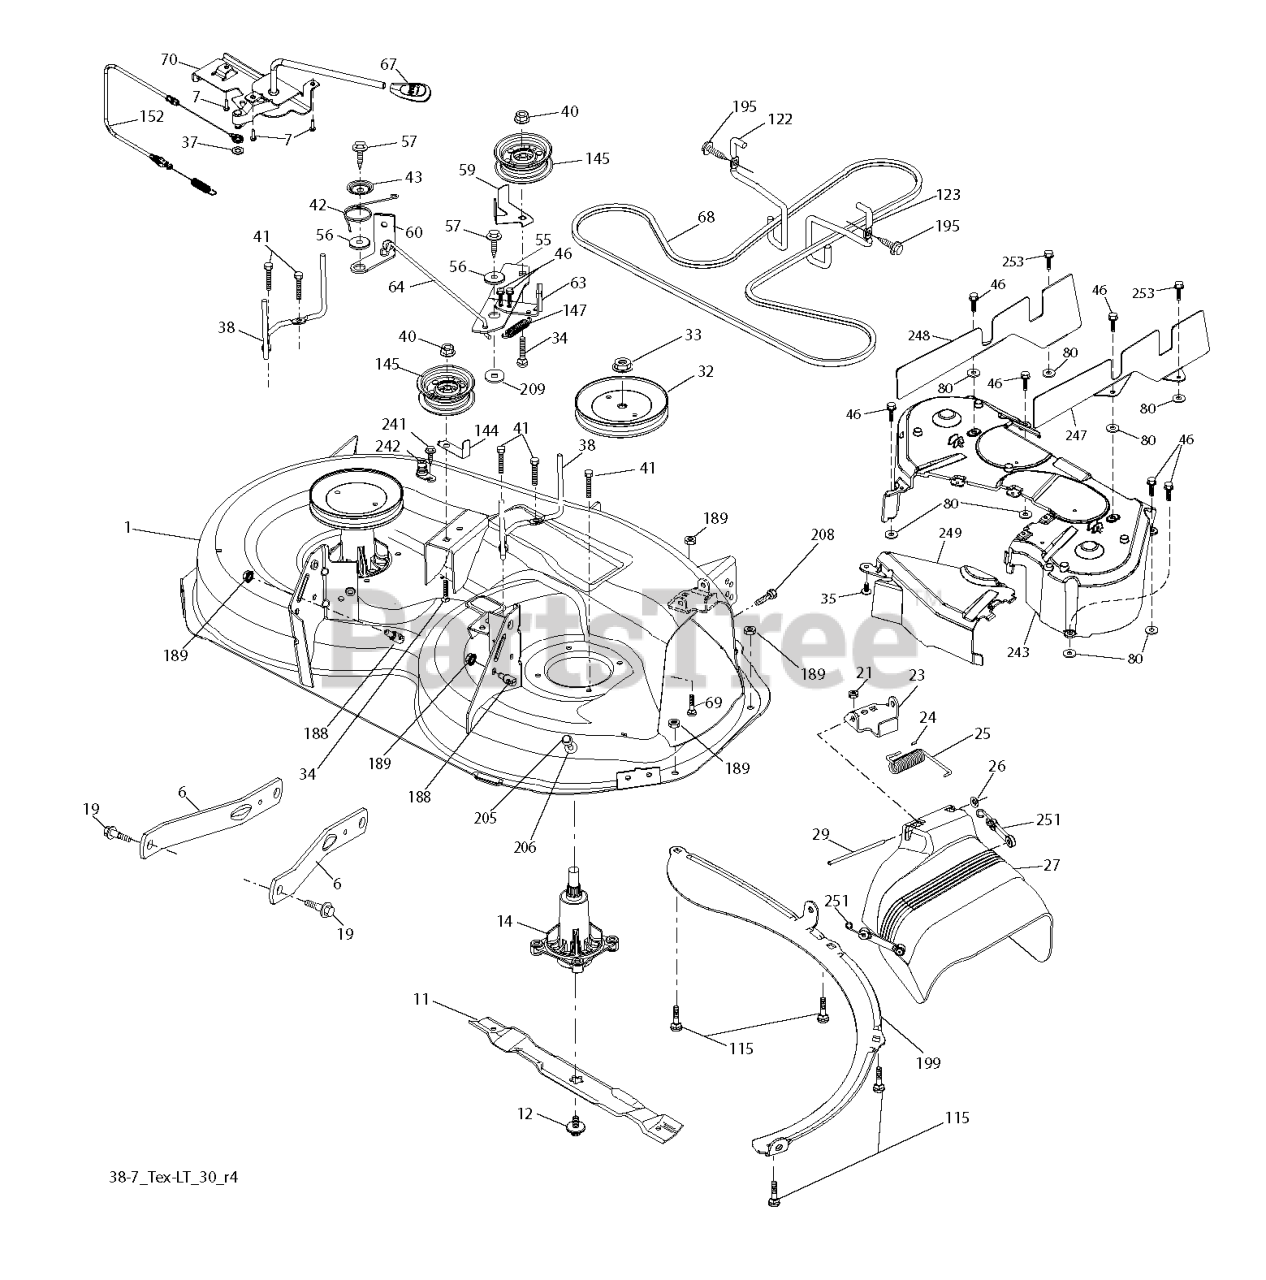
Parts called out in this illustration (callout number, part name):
6	SERVICE.KIT ARM.SUSPENSION.MOW
11	BLADE.2 IN 1.38"DECK.BLACK
12	SCREW.SEMS.7/16-20X1.HEX.HEAD
14	KIT.MANDREL.NONGREASE.TALL
19	BOLT.SHOULDER
23	BRKT.DEFLECTOR.38"2005+
24	CAP-SLEEVE LT
25	SPRING.TORSION.DEFLECT
26	NUT PUSH M
27	SHIELD.DEFLECTOR.MOWER.38"
27	Shields
32	SERVICE KIT PULLEY PULLEY.MAND
34	GSPW Bolts
35	FASTENER.XMAS.TREE
37	WASHER PLAIN WASHER 3/8 X 0.08
38	BELT KEEPER.MANDREL.38"COATED
40	NUT.HEX.FLANGE.3/8-16.LOCKNUT
41	BOLT.HEX.WASHR.HED.313-18X1.19
42	SPRING.TORSION.BRAKE
43	SRPING.TORSION.RETAINE
46	SCREW.1/4-20X5/8
55	SERVICE KIT IDLER.ARM
56	SPACER.RETAINER
57	SCREW 3/8-16X1
59	SERVICE KIT GUARD
60	ARM BRAKE MOWER RH 38"
63	BRAKE.ARM.LH.38"TEX.COATED
64	LINKAGE.BRAKE.ASM.ZINC
67	HANDLE.CLUTCH.CABLE.LT
70	CLUTCH.ASM.MANUAL.LT.PRED
80	PALNUT 1/4
115	BOLT ROUND HEAD SQUARE NECK BO
122	SERVICE KIT BELT KEEPER
123	SERVICE KIT KEEPER BELT KEEPER
144	SERVICE.KIT KEEPER BELT KEEPER
145	PULLEY.IDLER.FLAT
147	SPRING RETURN
152	CABLE.CLUTCH.MANUAL.
188	STUD.W/"D"ANTI-ROTATION
195	SCREW, 3/8-16X3/4
199	SERVICE KIT BAFFLE BAFFLE.VORT
205	SCREW
206	Washers
208	SCREW 3/8-16X1/2
241	SCREW.TT.#10-32X.5.3/8.FLANGE
242	PORT.WASHOUT
243	COVER.DECK.38"FRENCH.TEX
247	GUARD DECK.38IN.RH.ISO X431 BL
248	GUARD.DECK.38IN.LH.X431
249	COVER.CABLE.CLUTCH.38/42"TEX
251	KIT.STRAP.BUNGEE.DEFLECTOR.SVC
253	TULFLOK.RIVET
